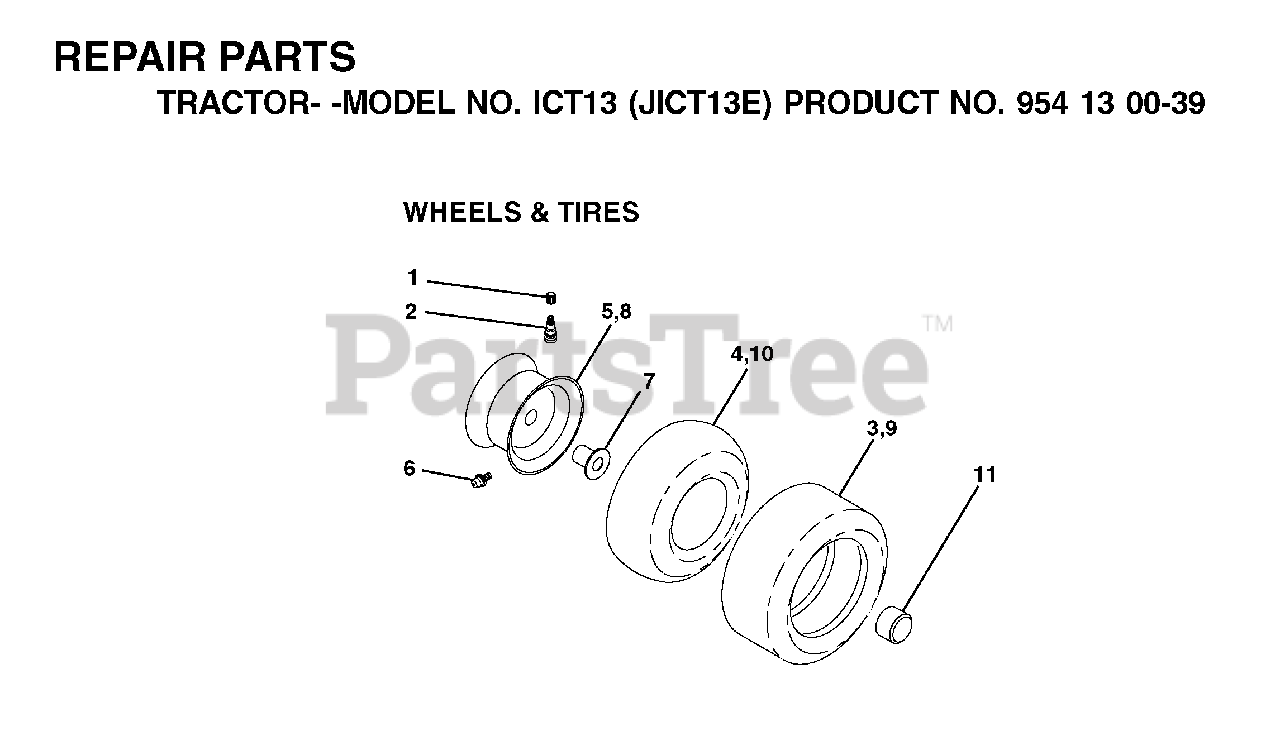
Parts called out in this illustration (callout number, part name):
1	VALVE CAP
2	VALVE STEM LT
3	TIRE HEAVY DUTY
4	TUBE.5.3/4.5/6
5	RIM ASM 6" FRONT SILVER
6	FITTING LT
7	BEARING T
8	RIM ASM 8" REAR SILVER
9	TIRE
10	TUBE
11	CAP, AXLE BLK
